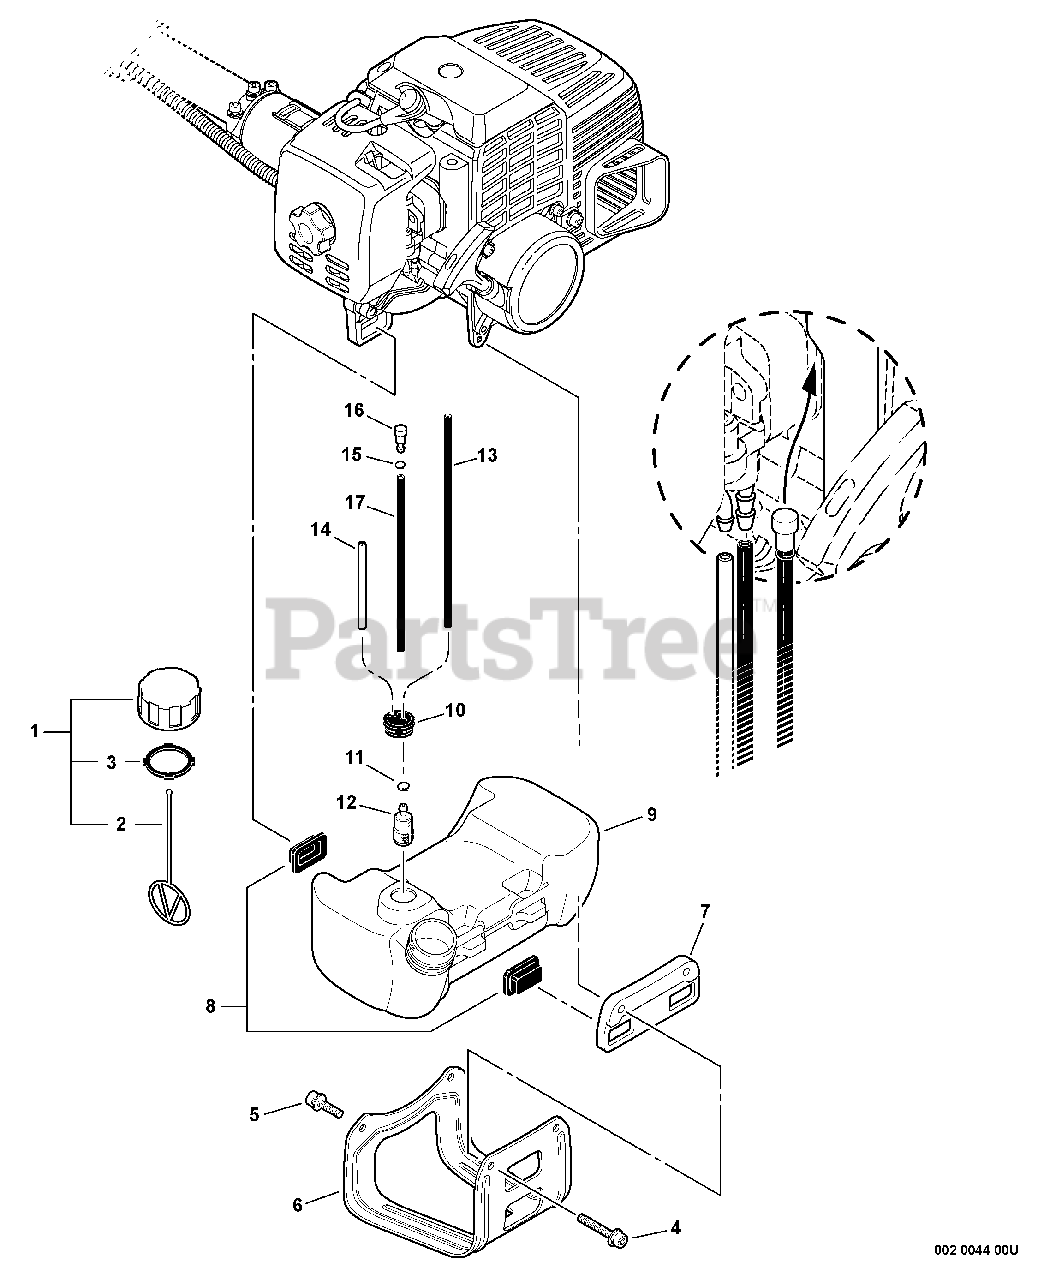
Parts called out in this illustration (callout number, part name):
1	CAP ASSY, FUEL
2	CONNECTOR, CAP L= 100 MM
3	GASKET, FUEL CAP
4	BOLT 5×20
5	BOLT 5×12
6	GUARD, FUEL TANK
7	BRACKET, FUEL TANK
8	CUSHION, FUEL TANK
9	TANK, FUEL
10	GROMMET, FUEL
11	CLIP 6 MM
12	FILTER, FUEL
13	PIPE, FUEL 3x-5x-180
14	PIPE, FUEL RETURN 3×6×70
16	VENT ASSY
17	PIPE, FUEL 3×5×120 BLACK
